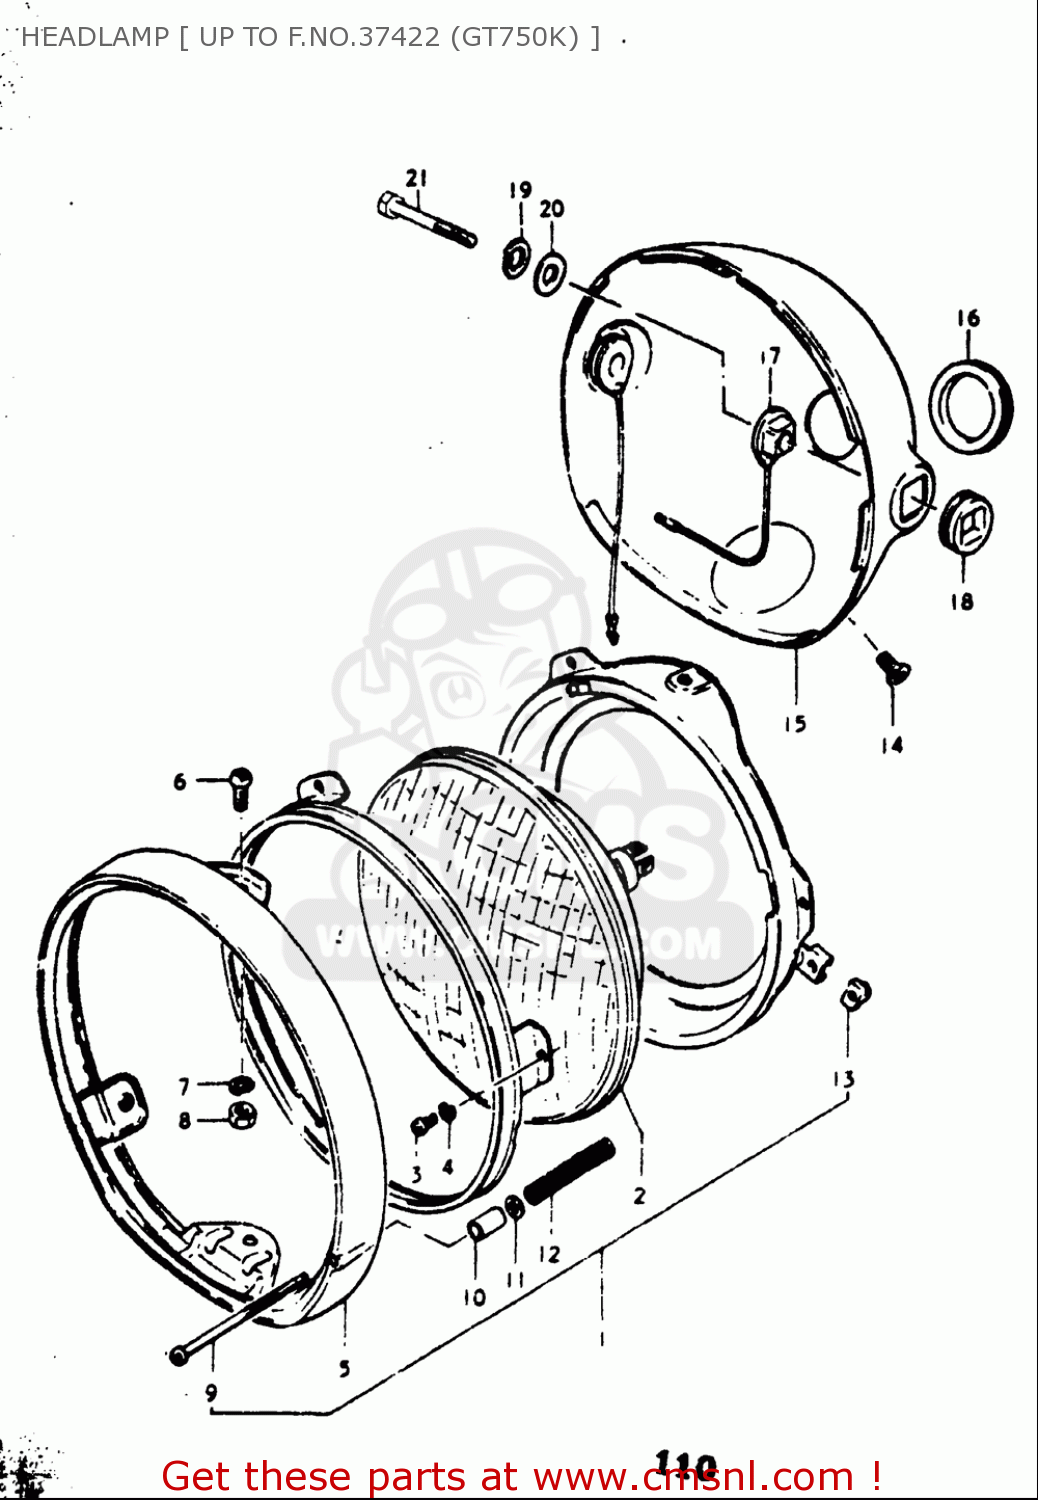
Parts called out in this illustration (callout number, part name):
3	SCREW
4	WASHER,LOCK
6	SCREW
7	WASHER,LOCK
8	NUT
9	SCREW
11	WASHER
13	NUT
14	SCREW
16	CUSHION,HOUSING
17	PIECE,ADJUSTER
19	WASHER,LOCK
20	WASHER
21	BOLT
